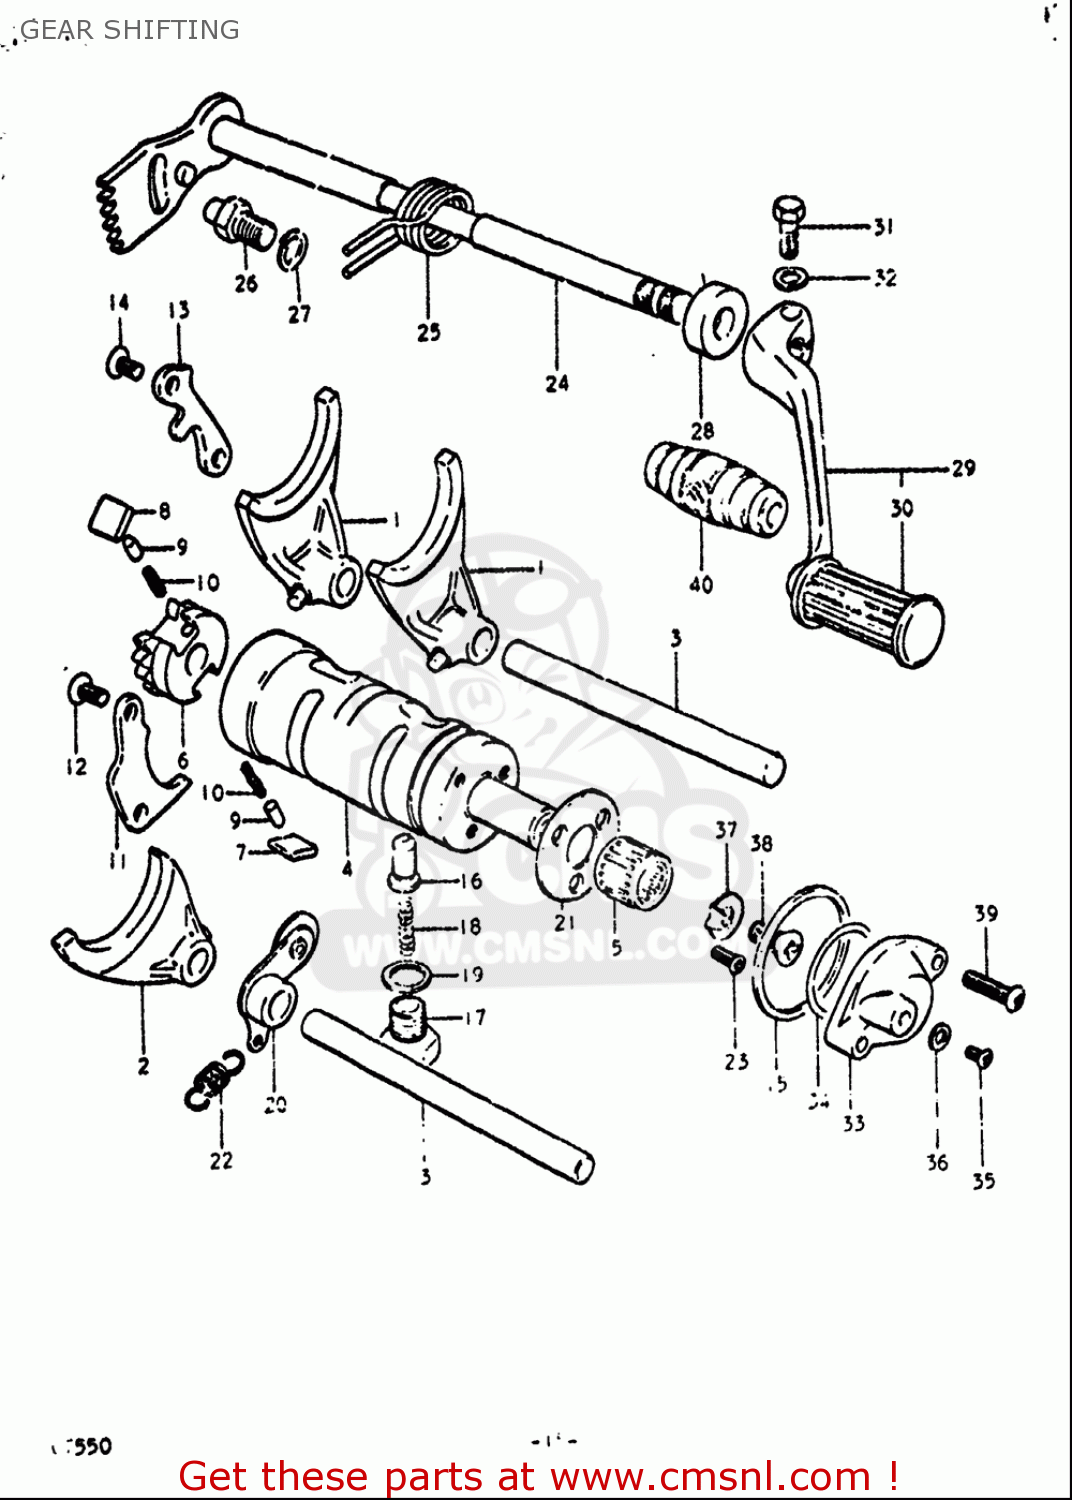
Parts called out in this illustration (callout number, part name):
1	FORK,GEAR SHIFT NO.1
2	FORK,GEAR SHIFT NO.3
3	SHAFT,GEAR SHIFT FORK
5	ROLLER BEARING (16X22X1
6	GEAR,GEAR SHIFT CAM DRIVEN
7	PAWL,GEAR SHIFT NO.1
8	PAWL,GEAR SHIFT NO.2
9	PIN(5X8)
10	SPRING
11	LIFTER,GEAR SHIFT PAWL
12	SCREW
13	GUIDE,GEAR SHIFT
14	SCREW
15	WASHER(40X45X1)
16	STOPPER,GEAR SHIFT CAM NO.2
17	HOLDER,GEAR SHIFT CAM STOP SPR
18	SPRING
19	GASKET(14X19.2X2) (NAS)
20	STOPPER,GEAR SHIFT CAM
22	SPRING
23	SCREW
25	SPRING
26	STOPPER,GEAR SHIFT ARM
27	WASHER,LOCK
28	SEAL,OIL (12X22X9)
29	LEVER ASSY,GEAR SHIFT
30	RUBBER,GEAR SHIFT PEDAL
31	BOLT
32	WASHER,LOCK
34	O RING(D:1.9,ID:27.7)
35	SCREW
36	WASHER
37	CONTACT,GEAR SHIFT SWITCH
38	SCREW
39	SCREW
40	RUBBER,GEAR SHIFT PEDAL
